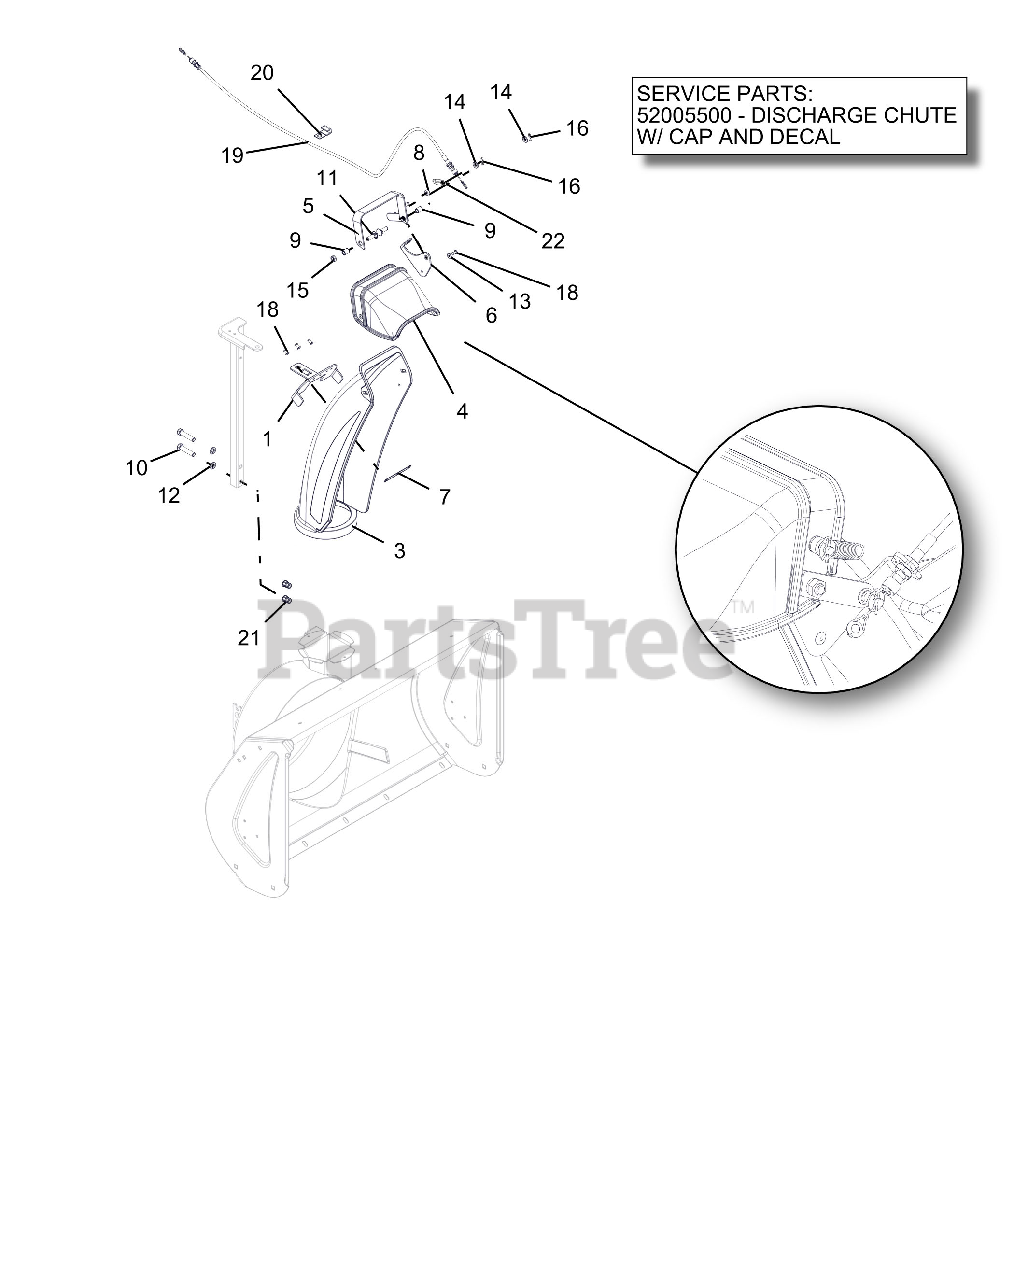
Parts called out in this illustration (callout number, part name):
1	CHUTE MOUNT BRACKET
3	CHUTE, PLASTIC DISCHARGE LONG
4	DEFLECTOR CAP, PLASTIC
5	WELDMENT, DEFLECTOR CAP SNOTEK
6	BRACKET, CABLE ANCHOR SNOTEK
7	PLATE,CHUTE MOUNT BACKING
8	BSHG-SLV .265X.500X.219
9	BSHG-SLV .330X.455X.550
10	@BLT-HEX .38-16X1.75 GR5 YWZC
11	BLT,RNHDRECSHNK .31-18X1.00
12	@WSHR-LK .38X.094 REG YWZC
13	WSHR-FL-STL .196X.500X.06 YZ
14	@WSHR-FL-STL.281X.62X.065 YWZC
15	@NUT-LK-CTR-JAM .31-18 YWZC
16	PIN-HAIR INT .06X.18X.77
18	RIVET, #66 STEEL POP PD BLACK
19	CABLE, DEFLECTOR CAP SNO-TEK
20	J-CLAMP
21	NUT, THREADED INSERT .38-16
22	SPRG, TENSION .052X.520X1.74
23	CHUTE, REMOTE DISCHARGE W/CAP
